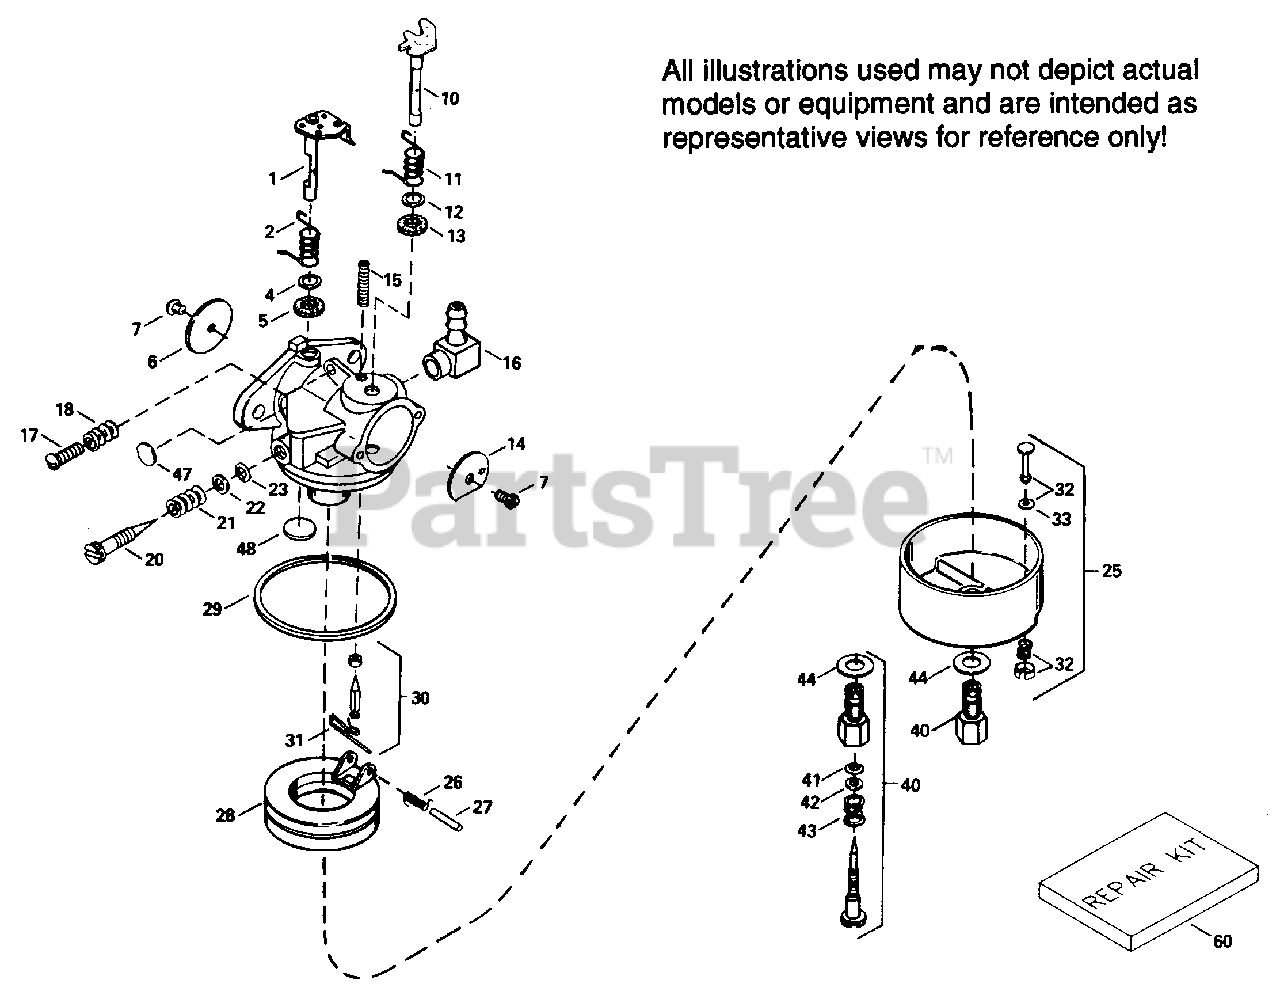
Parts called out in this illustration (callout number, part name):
1	Throttle Shaft & Lever Assy.
2	Throttle Return Spring
4	Dust Seal Washer
5	Dust Seal (Throttle)
6	Throttle Shutter
7	Throttle & Choke Shutter Screw
10	Choke Shaft & Lever Assy.
11	Choke Return Spring
12	Dust Seal Washer (Choke)
13	Dust Seal (Choke)
14	Choke Shutter
15	Choke Positioning Spring
16	Fuel Fitting
17	Idle Speed Screw
18	Tension Spring
20	* Idle Mixture Screw
21	Idle Tension Spring
22	Washer, Idle Screw
23	* O Ring, Idle Screw
25	Float Bowl
27	* Shaft, Float
28	Float
29	* O Ring, Float Bowl to Body
30	* Inlet Needle, Seat & Clip (Incl. 31)
31	Spring Clip
40	* Main Adj.Screw Assy. Incl. 41 thru 44
41	* O Ring, High Speed Mixture Screw
42	Washer, High Speed Mixture Screw
43	Tension Spring, High Speed Mixture Sc rew
44	* Bowl Nut Washer
47	* Welch Plug, Idle Mixture Well
48	* Welch Plug, Atmospheric Vent
60	Repair Kit (Incl. Parts Marked with * )
